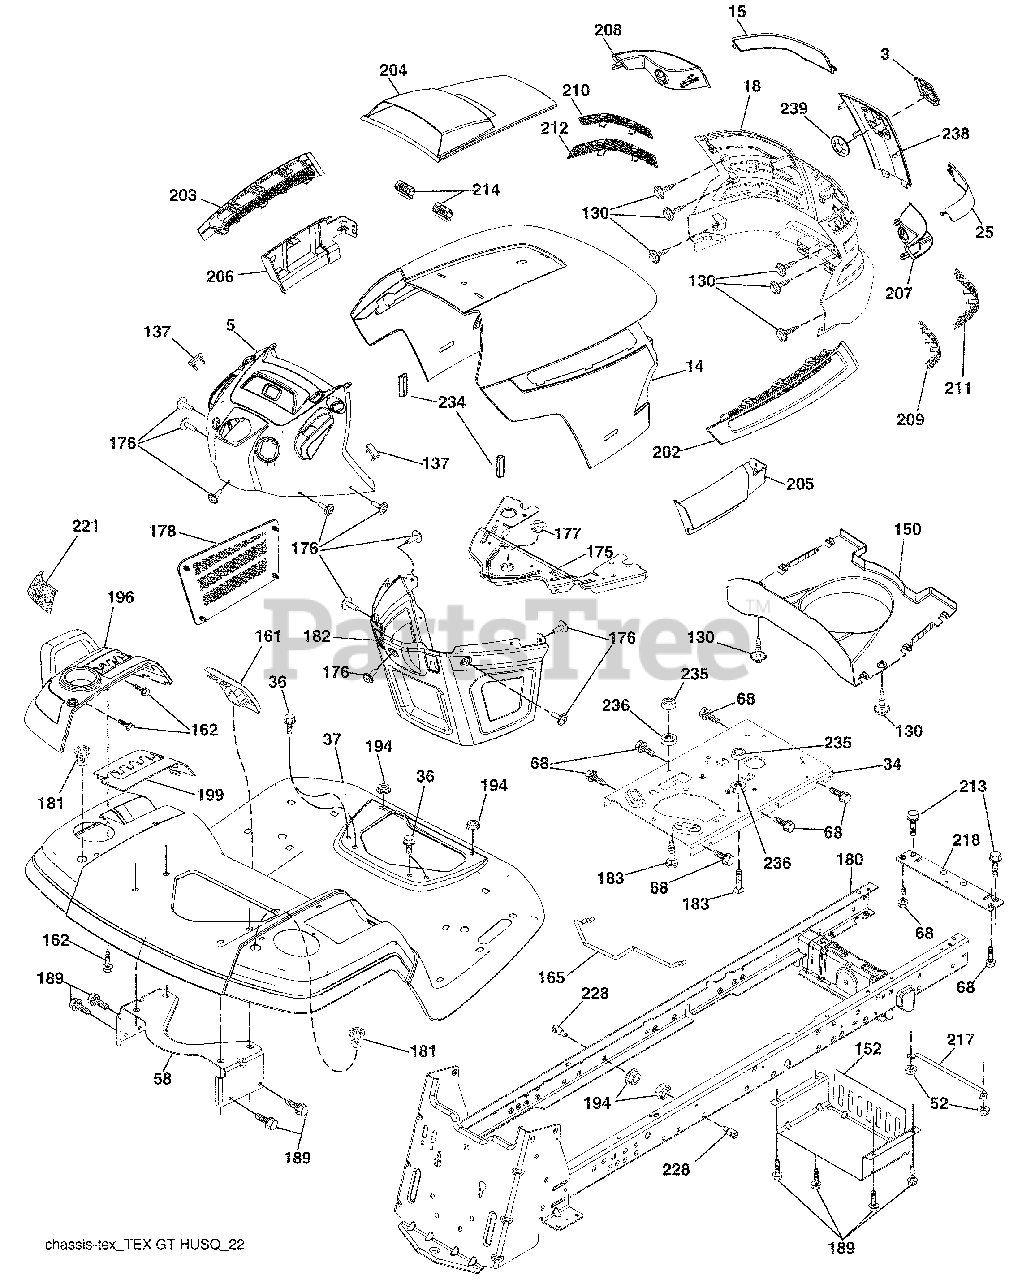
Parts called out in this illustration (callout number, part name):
3	Logo Husq
14	Hood
34	Plate Engine
36	Screw 5/16-18 x 3/4
37	Fender
52	Nut Lock 5/16-18
58	Bracket Fender
68	Screw 5/16-18 x 1/2
130	Screw #10 x 0.750
137	Bumper Dash
150	Duct Heat Hood
152	Shield Browning/Debris
161	Console Fuel Window
162	Screw Hex Wsh Hi-Lo 1/4 x 1/2
165	Bracket Support Tank
175	Crossmember
176	Screw 10-24 x 5/8 Rnd Qdrx
177	Bushing Steering
178	Cargo Asm. Net
180	Chassis
181	Bushing Mtg. Fender Crgo.
182	Dash Lower
183	Bolt 5/16-18 x 1-1/4
189	Screw 5/16-18 x 3/4
194	Nut Lock Hex Flange 5/16-18
196	Console Asm. Deck Lift
199	Plate Deck Lift
202	Vent Side Hood RH
203	Vent Side Hood LH
204	Vent Asm Hood Top
205	Skirt Hood Side RH
206	Skirt Hood Side LH
209	Insert Hex Top RH
210	Insert Hex Top LH
211	Insert Hex Bottom RH
212	Insert Hex Bottom LH
213	Bolt Hex Hd 5/16-18 unc x 3/4
214	Clip Retainer
217	Rod Pivot Hood
221	Reflector LH
228	Stud Fastner
234	Bumper Hood
235	Spacer Fender
236	Nut Lock 5/16-18 unc
